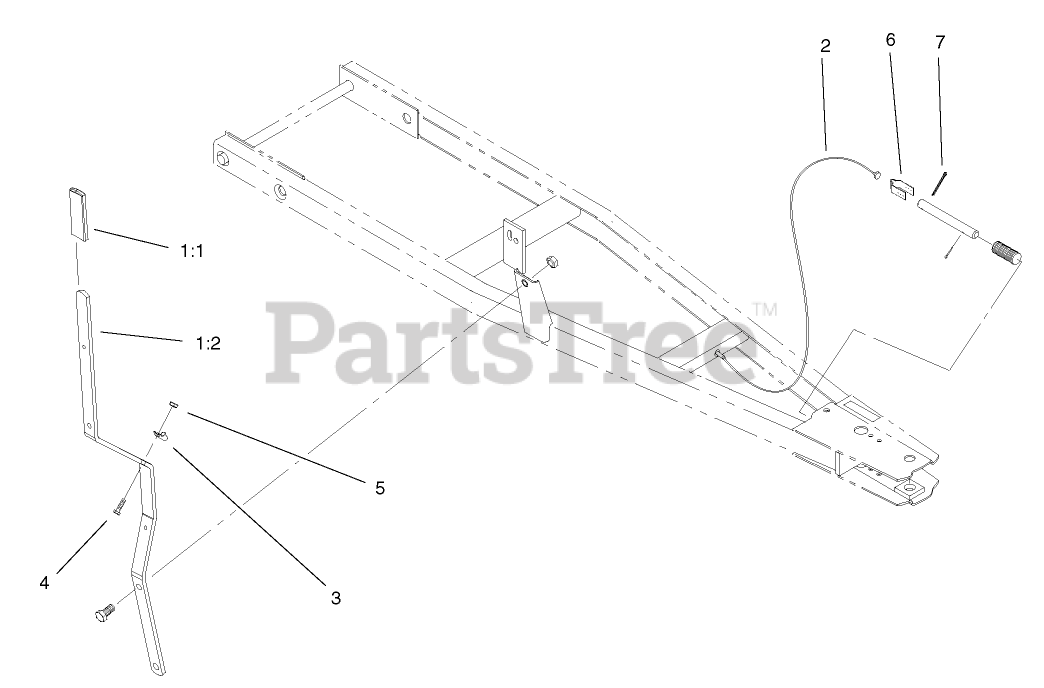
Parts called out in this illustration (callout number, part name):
1:1	GRIP
1:2	LEVER-INDEX
2	CABLE-INDEXING, DOZER
3	R-CLAMP
4	SCREW-HH
5	NUT-LOCK
6	BRACKET - CABLE END
7	PIN-COTTER
